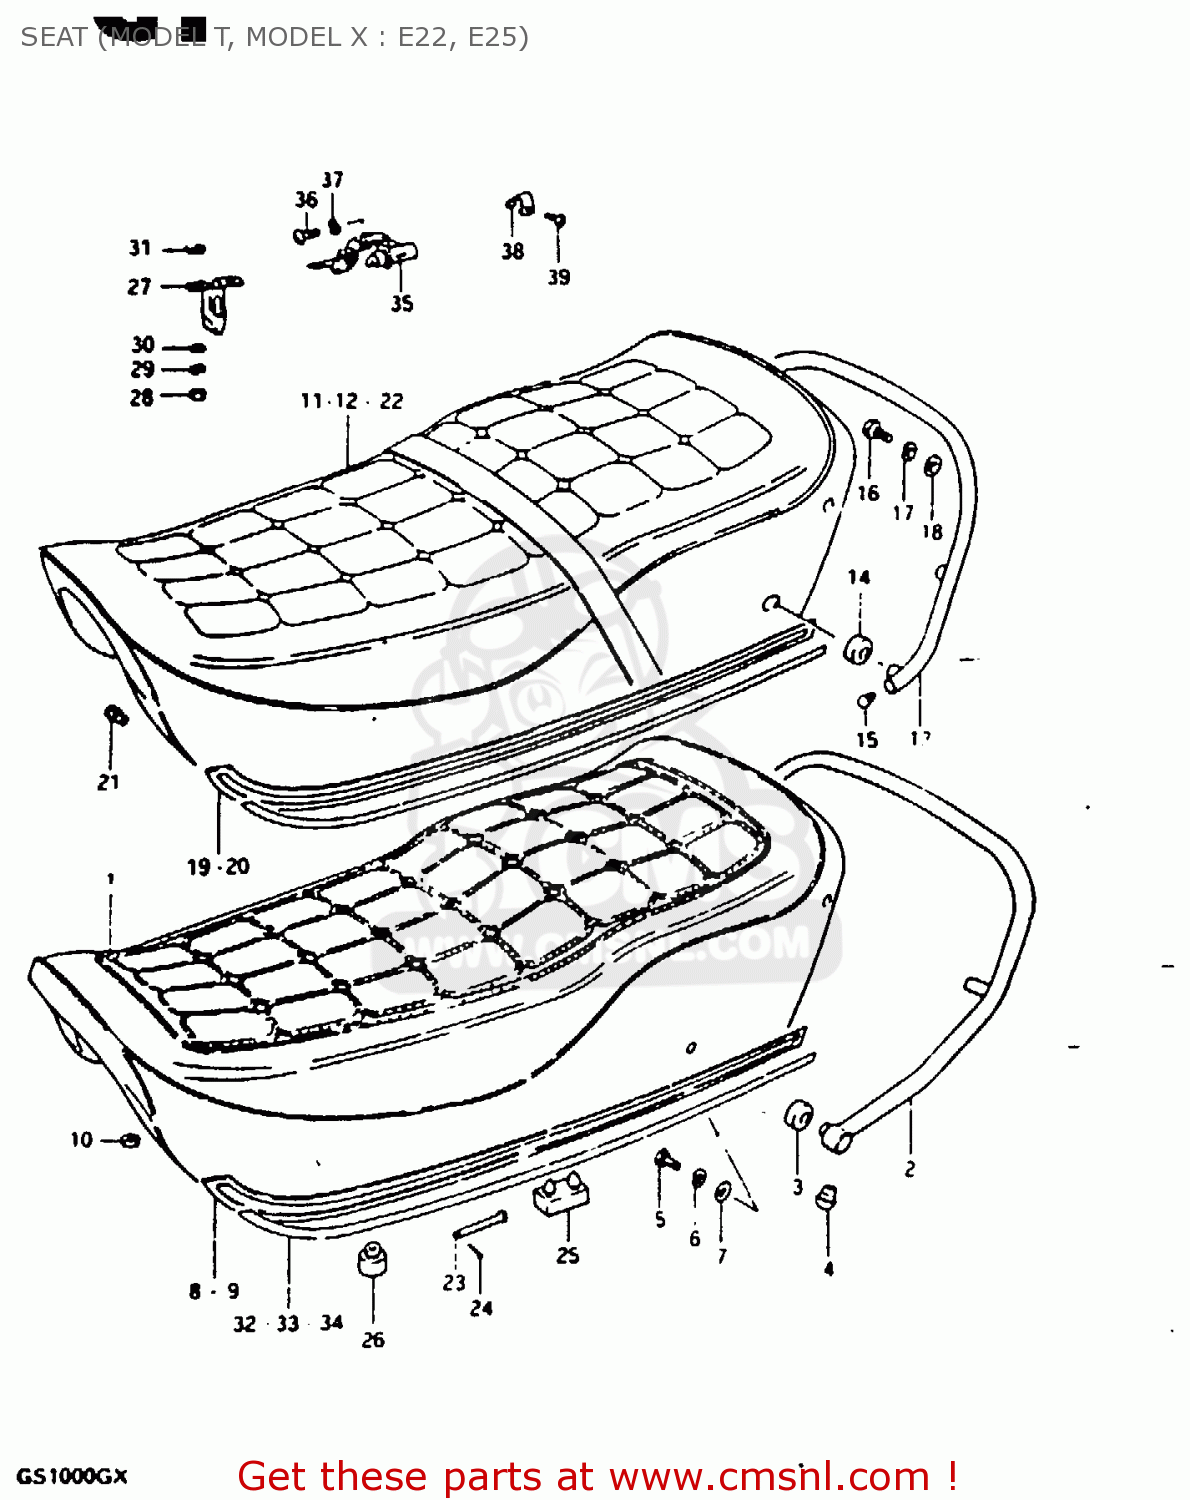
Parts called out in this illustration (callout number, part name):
11	SEAT ASSY (FLAT TYPE)
12	SEAT ASSY
13	HANDLE, PILLION RIDER
14	CUSHION
15	END,SHEET HANDLE
16	BOLT
17	LOCK WASHER
18	WASHER
19	MOLE,R
20	MOLE,L
21	NUT
23	PIN
24	PIN
25	CUSHION
26	CUSHION
27	STRIKER,SEAT LOCK
28	NUT
29	LOCK WASHER
30	WASHER 6MM
31	WASHER (6.5X20X1.2)
32	TAPE SET
33	TAPE SET, SEAT MOULDING
34	TAPE SET, SEAT MOULDING
35	LOCK ASSY,SEAT
36	SCREW
37	LOCK WASHER
38	SPRING,HELMET HOLDER
39	SCREW
